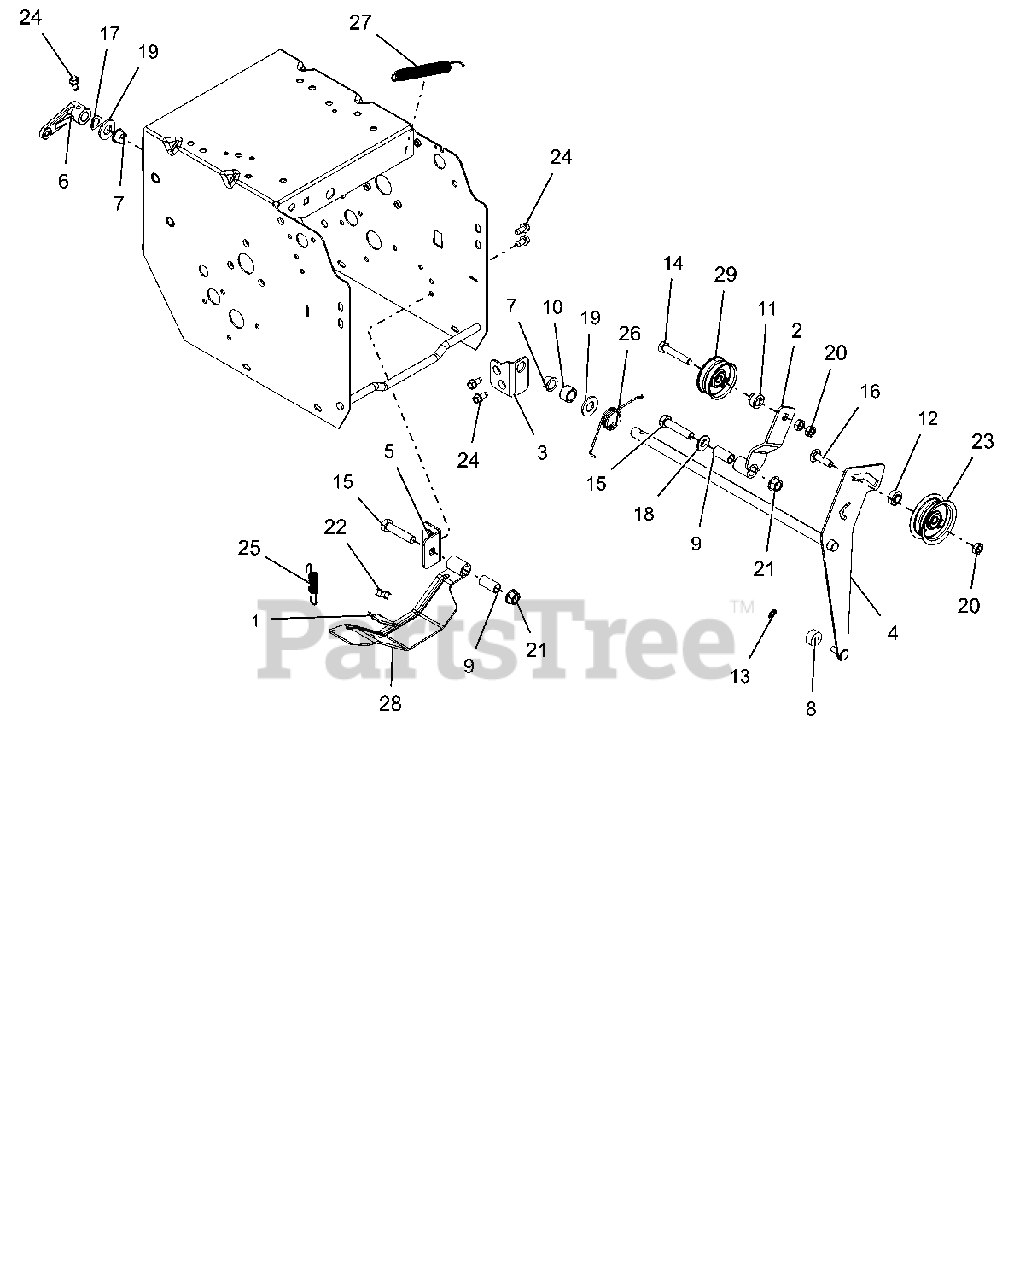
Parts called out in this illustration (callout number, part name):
1	PAD, BRAKE
2	ARM, TRACTION IDLER
3	BRACKET, MOUNT - IDLER ARM
4	WELDMENT, ATTACHMENT IDLER ARM
5	BRACKET, MOUNT - BRAKE
6	ARM, CLUTCH - ATTACHMENT
7	BUSHING, POLYLINER-.50 SPLIT
8	BSHG,SLV .265 X .625 X .375
9	BSHG-SLV .385X.500X1.045
10	BSHG-SLV .510X.751X.475
11	SPCR, BRG .315X.500X.481X.281
12	SPCR, BRG .315X.500X.358X.281
13	RG-RTNG-EXT .250X.010
14	@BLT-HEX .31-18X1.75 GR5 YWZC
15	@BLT-HEX .38-16X1.75 GR5 YWZC
16	BLT-RDHDSQSHNK.31-18X1.13 G5YZ
17	WSHR-WAVE .50X.75X.015 .13FRHT
18	@WSHR-FL-STL.406X.812X.065 YWZ
19	@WSHR-FL-STL.531X1.06X.095YWZC
20	@NUT-LK-CTR-JAM .31-18 YWZC
21	@NUT-LK-TOP-FLG .38-16 YWZC
22	RVT-POP .187 YZ
23	IDLER, FLAT - 2.00"
24	SCR-TAP .25-20X.50 HWH TR YWZ
25	SPRING-EXT .437 X .438 X 2.64
26	SG-TORS .075 X .955
27	SPRING, EXTENSION
28	BRAKE ARM W/PAD
29	IDLER, FLAT - 1.875"
